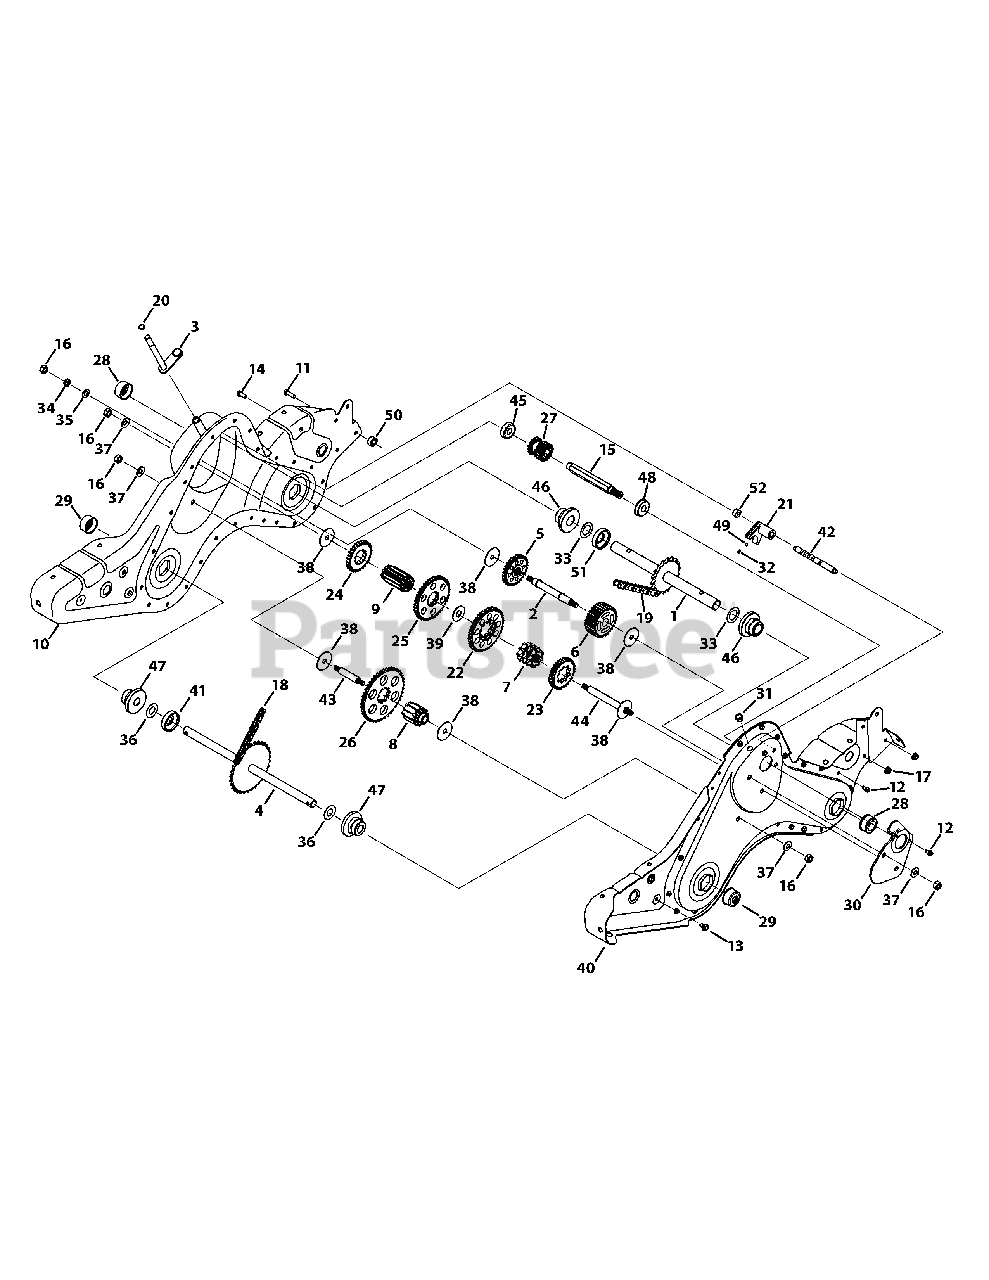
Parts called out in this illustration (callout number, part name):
1	Tine Shaft Assembly
2	Jack Shaft Assembly
3	Shift Input Shaft Assembly
4	Wheel Shaft Assembly
5	Reverse Idler Gear Assembly
6	Tine Idler Gear Assembly
7	Tine Input Sprocket Assembly
8	Wheel Input Sprocket Assembly
9	Gear Assembly
10	RH Chain Case Housing Assembly
11	Hex Screw, 5/16-18 x 1.00
12	Screw, 1/4-20 x 0.500
13	Screw, 5/16-18 x 0.625
14	Hex Screw, 5/16-18 x .75
15	Input Shaft, .75
16	Hex Nut, 7/16-20
17	Flange Lock Nut, 5/16-18
18	Endless Chain, 420 x 50
19	Endless Chain, 50 x 54
20	Snap Ring, .500
21	Clutch Collar
22	Gear Spur, 44T
23	Gear Spur, 30T
24	Gear Spur, 30T
25	Gear Spur, 44T
26	Gear Spur, 44T
27	Gear Spur, 16T
28	Shaft Seal, 1.0
29	Shaft Seal, .75
30	Positioner Gear Bracket
31	Tapered Cap Plug
32	Compression Spring, .230
33	Flat Washer, 1.03 x 1.62 x .03
34	Lock Washer, 7/16
35	Flat Washer, .474 x .879 x .064
36	Flat Washer, .760 x 1.50
37	Bell Washer,.45 x 1.00 x .062
38	Thrust Washer, .445 x 1.92 x .060
39	Flat Washer, 1.595 x .635 x .062
40	LH Chain Case Housing
41	Spacer, .75 x 2.0 x .50
42	Shaft Detent, .5
43	Jack Shaft, .625 x 2.385
44	Jack Shaft, .6250 x 5.0050
45	Ball Bearing, 17 x 40 x 12
46	Flange Bearing, 1.0 x 2.5 x 1.38
47	Flange Bearing, .75 x 2.5 x 1.38
48	Ball Bearing, 17 x 40 x 12:6203
49	Detent Ball, .250
50	Spacer, .315 x .750 x .375
51	Spacer, 1.0 x 2.0 x .5
52	Spacer, .505 x .88 x .440
